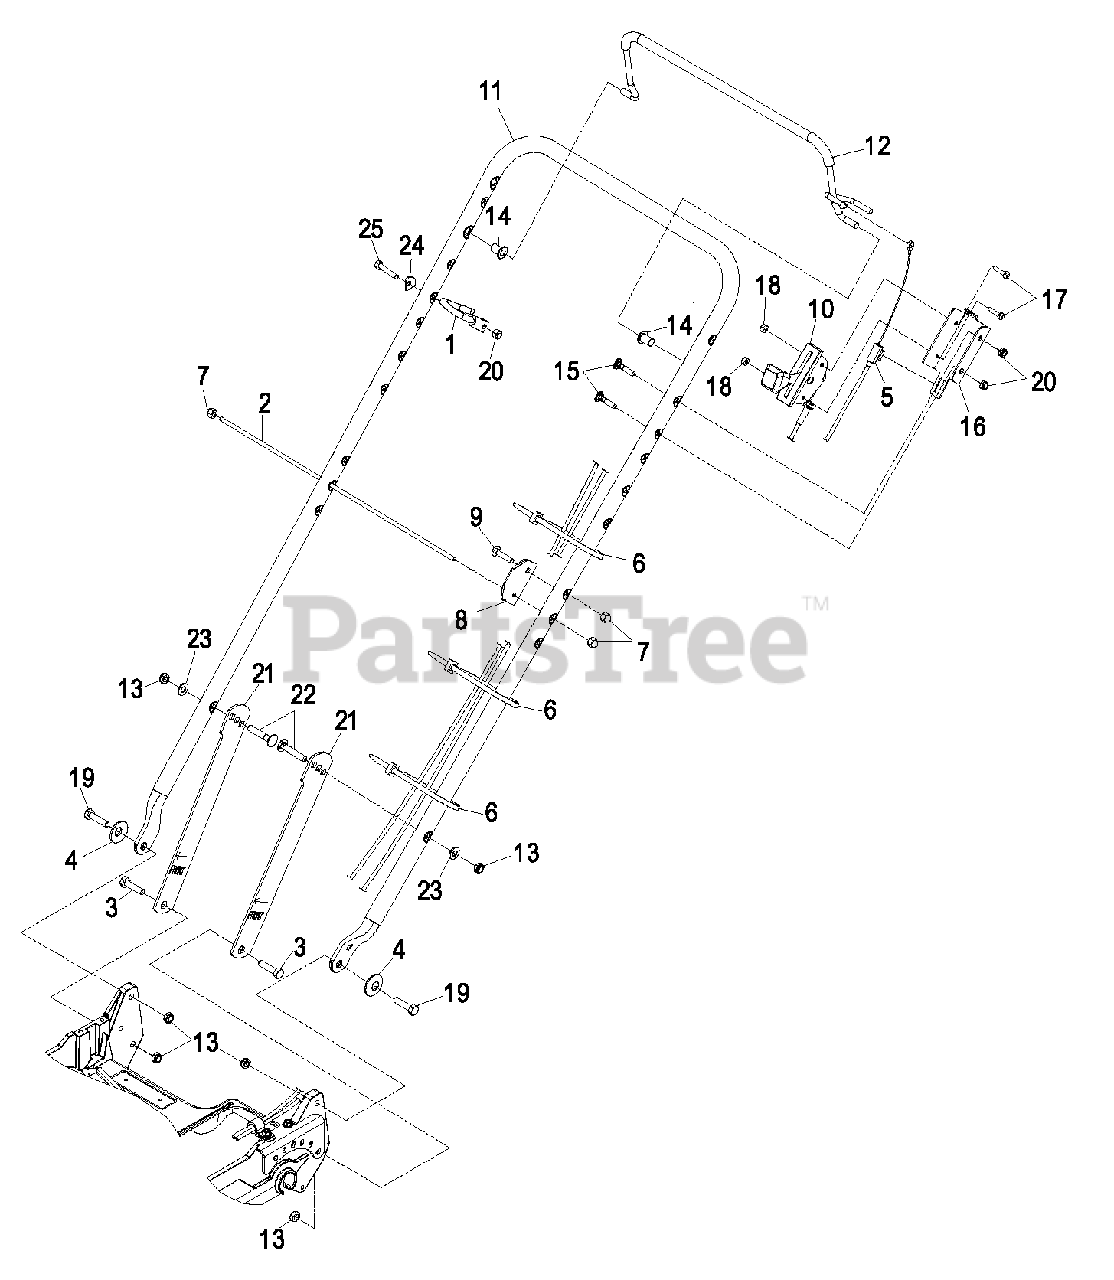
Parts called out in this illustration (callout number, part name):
1	GUIDE-ROPE
2	ROD, BAG SUPPORT
3	SCREW-HH
4	WASHER-BELLEVILLE
5	CABLE,BRAKE KAWASAKI
5	CABLE, BRAKE HONDA
6	TIE-CABLE
7	NUT-CAP
9	SCREW-CARR
10	CABLE,THROTTLE KAWASAKI
13	NUT-LOCK, NI
14	BUSHING
15	SCREW-CARR
16	BRACKET, THROTTLE
17	SCREW-PPH
18	NUT-LOCK, NI
19	SCREW-HH
20	NUT-LOCK, NI
21	Latch, Handle
22	BOLT-CARR
23	WASHER-PLAIN
24	WASHER
25	SCREW-HH
